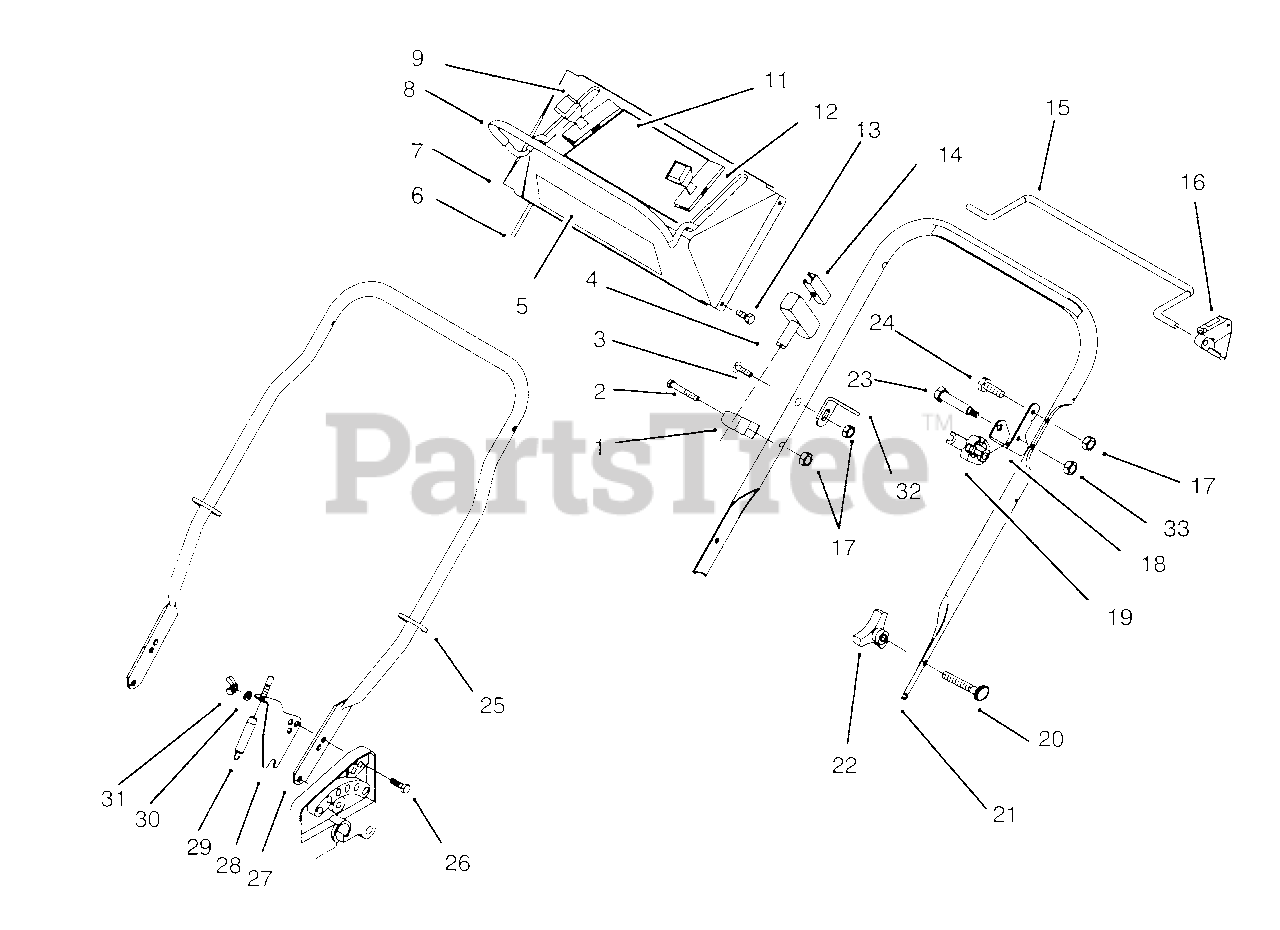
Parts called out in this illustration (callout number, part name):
1	Guide-Rope
4	Handle-Rope
5	Decal-Control Panel
6	Cable-Brake
7	Panel-Control (Model No. 10415)(Incl. Ref. #11)
8	Bail-Brake
9	Control Ground Speed (Model No. 10515 & 10520)
11	Decal-Control Panel (Model No. 10415)
12	Control-Throttle
14	Insert-Handle
15	Bail-Control (Model No. 10515 & 10520)
16	Stop-Pivot (Model No. 10515 & 10520)
18	Bracket-Cam
19	Brake-BBC Cam
20	Screw-Handle
21	Handle-Upper
22	Knob-Handle
23	Bolt-Shoulder
24	Screw-Hex. Hd.
25	Tie-Cable
26	Bolt-Carriage
27	Handle-Lower
28	Bracket-Traction Cable (Model No. 10515 & 10520)
29	Cable-Traction (Model No. 10515 & 10520)
32	Bracket- Cable
33	Nut-Lock
